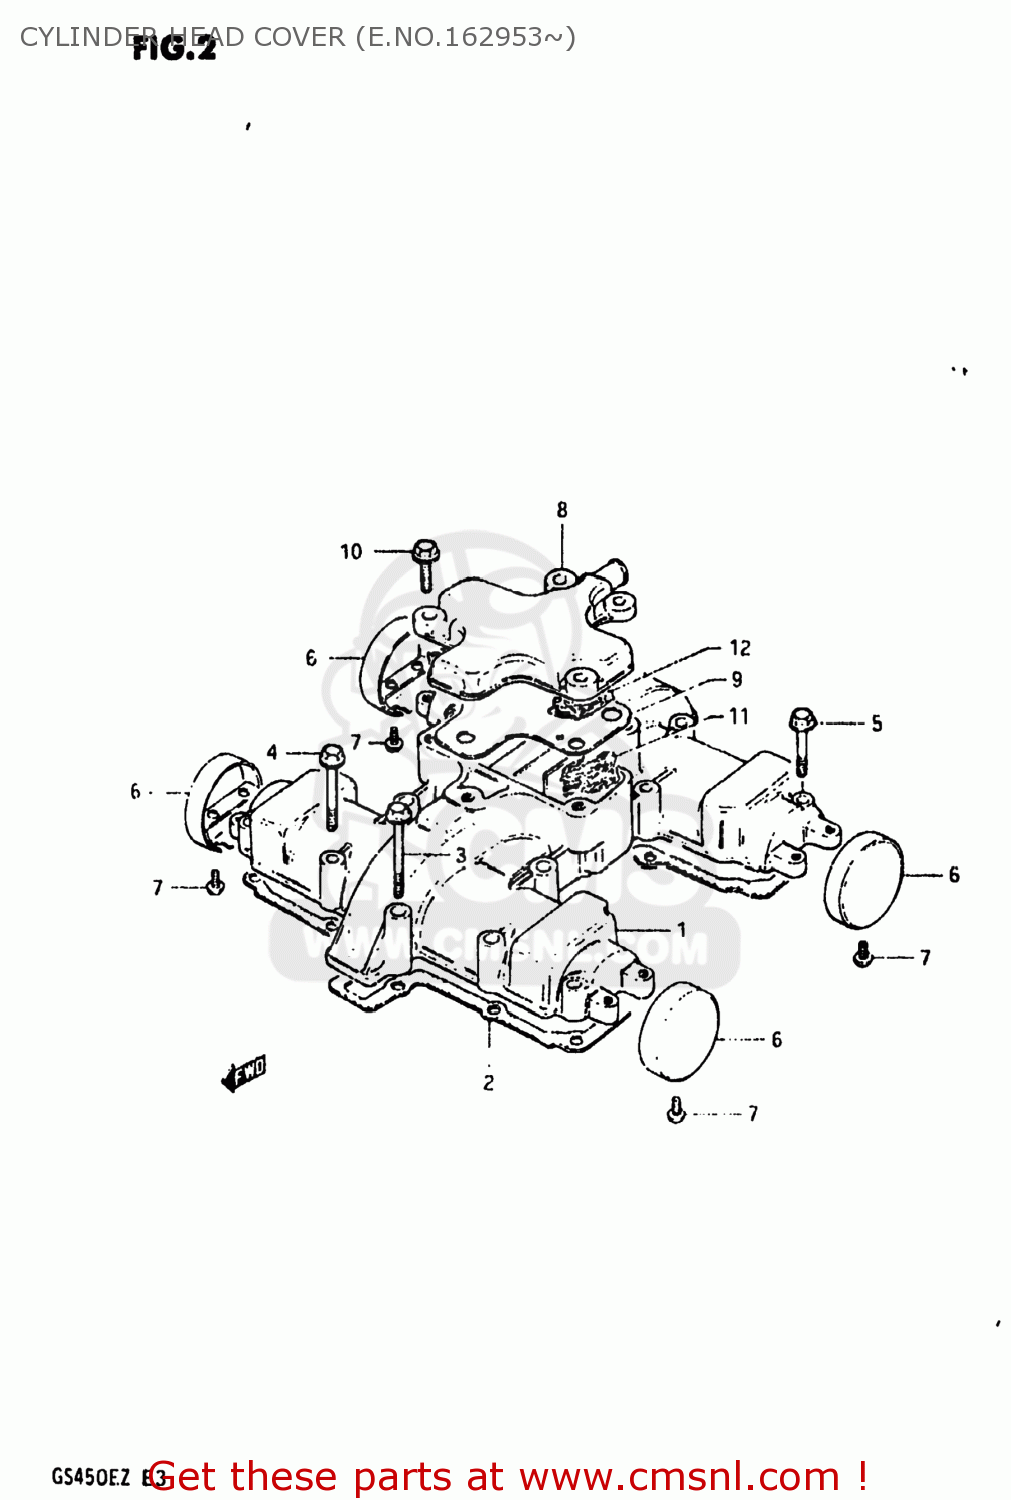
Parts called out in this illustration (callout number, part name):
1	COVER,CYLINDER HEAD
2	GASKET,CYLINDER HEAD COVER (MCA)
3	BOLT,UNDER
4	BOLT
5	BOLT
6	CAP,CYLINDER HEAD COVER
7	SCREW
8	COVER,BREATHER
9	GASKET (MCA)
10	BOLT,REAR
11	COVER,BREATHER
12	SEPARATOR,OIL BREATHER
